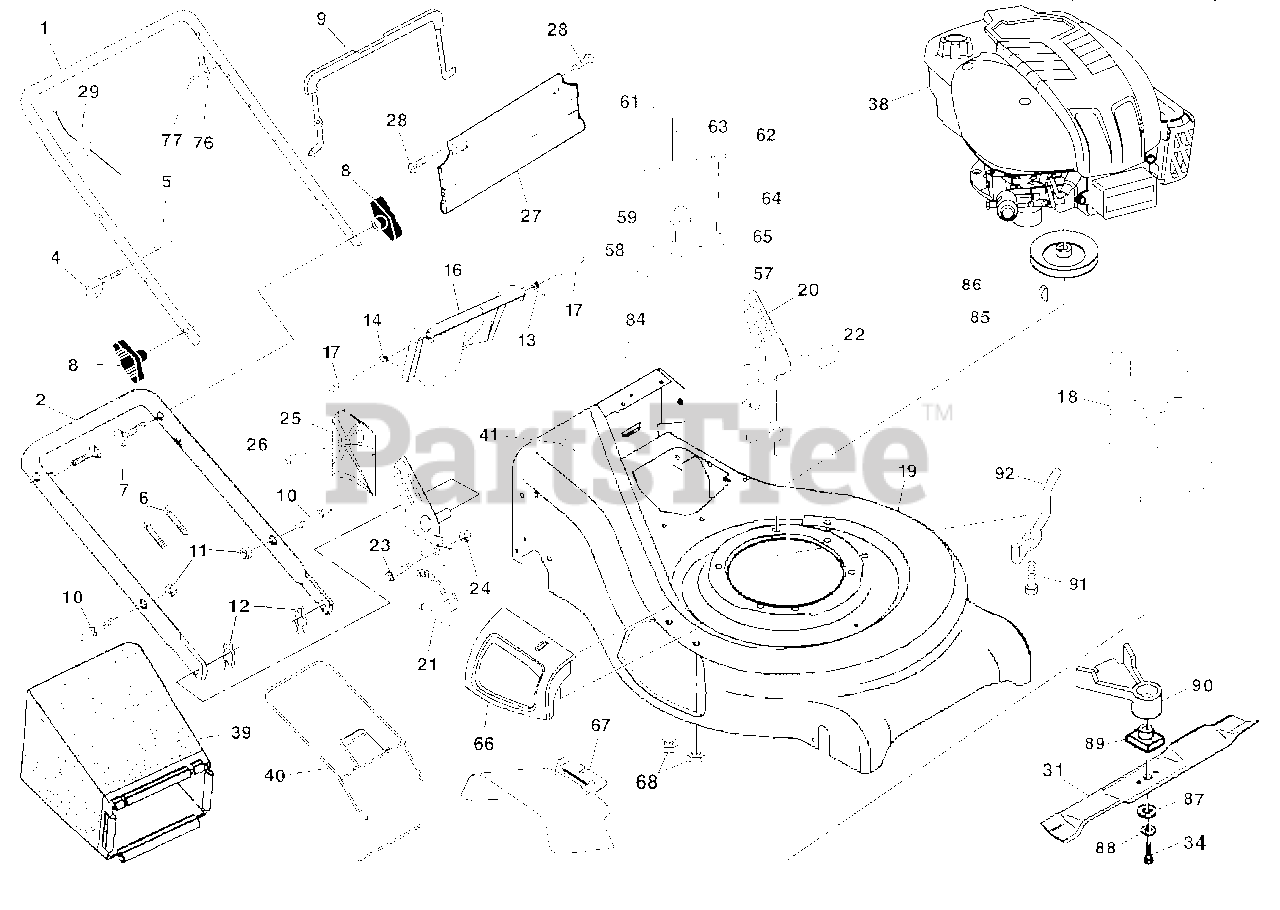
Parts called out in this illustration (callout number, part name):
1	Drive Control Assembly
2	Control Bar, Drive
3	Nut, Hex
4	Screw
5	Cover Drive
6	Screw, Threaded, Rolled #10-25 x .50
7	V-Belt
8	Nut, Flangelock, Zinc Plated 3/8-16
9	Pulley, Drive
10	Bearing, Ball
11	Screw
12	Seal, Output Shaft
13	Gear Case Assembly, Complete
14	Pin, Spring, Thrust
15	Washer, Hardened
16	Rod, Connecting
17	Spring, Extension
18	Spring, Selector
19	Knob, Selector Spring
20	E-Ring 7/8
21	Bearing, Support
22	Bearing, Ball
23	Retainer, Drive Assembly
24	Screw, Tapping, Hex Head 1/4-20 x .75
25	Bushing
26	Shaft, Output
27	Washer, Shim (as required)
28	E-Ring 7/16
29	Cover, Dust, Wheel
30	Gear, 24 Teeth
31	Nut, Flangelock
32	Wheel 9 x 2
33	Nut, Flangelock 3/8-16
34	Hubcap, Mag, Platinum
35	Shaft Assembly, Rear
36	Shaft Assembly, Front
37	Retainer, Front Shaft
38	Screw #12 x 5/8
39	Clip, Retainer
40	Wheel 8 x 2
41	Case, Lower
42	Case, Upper
43	Washer
44	Shaft, Input
45	Wire, Formed
46	Washer
47	Screw
48	Seal, Input Shaft
49	Pinion, Gear
50	Retainer, Drive, RH
51	Pawl
52	Spring, Torsion
53	Disc, Drive
54	Seal, Friction
55	Pinion Assembly, RH
56	Pinion Assembly, LH
57	Washer
58	Retainer, Drive, LH
